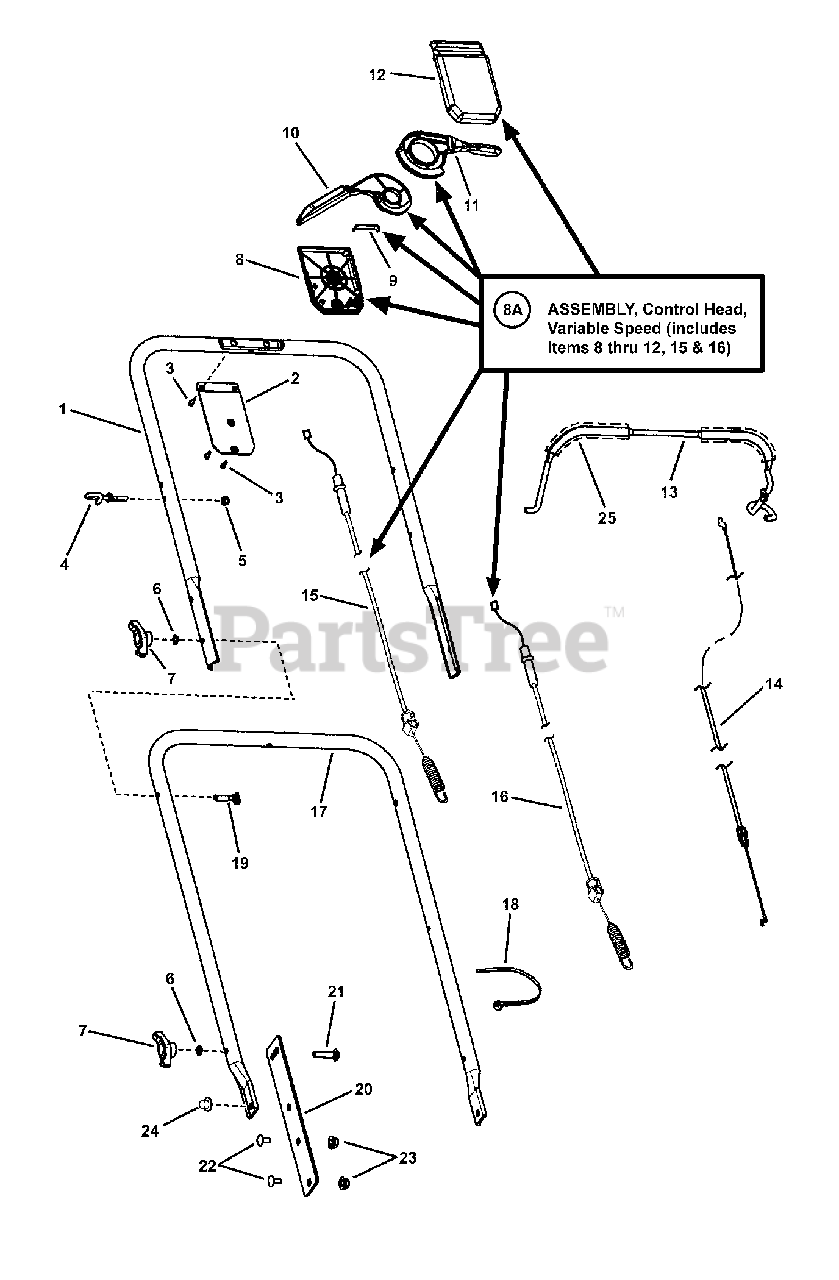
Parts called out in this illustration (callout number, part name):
1	HANDLE, Upper
2	PLATE, Control Panel
3	SCREW, #8-16 Recessed Pan Head (Torxplus)
4	GUIDE, Rope
5	NUT, 1/4-20 Hex Nyloc
6	WASHER, 5/16 Internal Tooth Lock
7	KNOB, 5/16-18 Wing (Black)
8	CASE HALF, Bottom
8A	ASSY, Control Head Variable Speed (Incl. 8, 9, 10, 11, 12, 15 & 16)
9	SPRING STEEL
10	CLUTCH LEVER, Silver
11	ASS'Y., Speed Lever/Friction Material (Snapper)
12	CASE HALF, Top, Variable Speed
13	BAIL, Brake
14	* CABLE, Zone Control
15	* CABLE, Clutch
16	* CABLE, Speed
17	HANDLE, Lower
18	WIRE TIE, 11 Inch Black Nylon
19	BOLT, 5/16-18 x 2" Curved Head Square Neck, GR 2
20	BRACKET, Lower Handle, Black Textured
21	BOLT, 5/16-18 x 1-1/2" Round Head Square Neck, GR 5
22	BOLT, 5/16-18 x 5/8" Round Head Short Square Neck Carriage
23	NUT, 5/16-18 Hex Flange Lock, GR 5
24	PUSHNUT, 3/8"
25	FOAM GRIP, 7"
